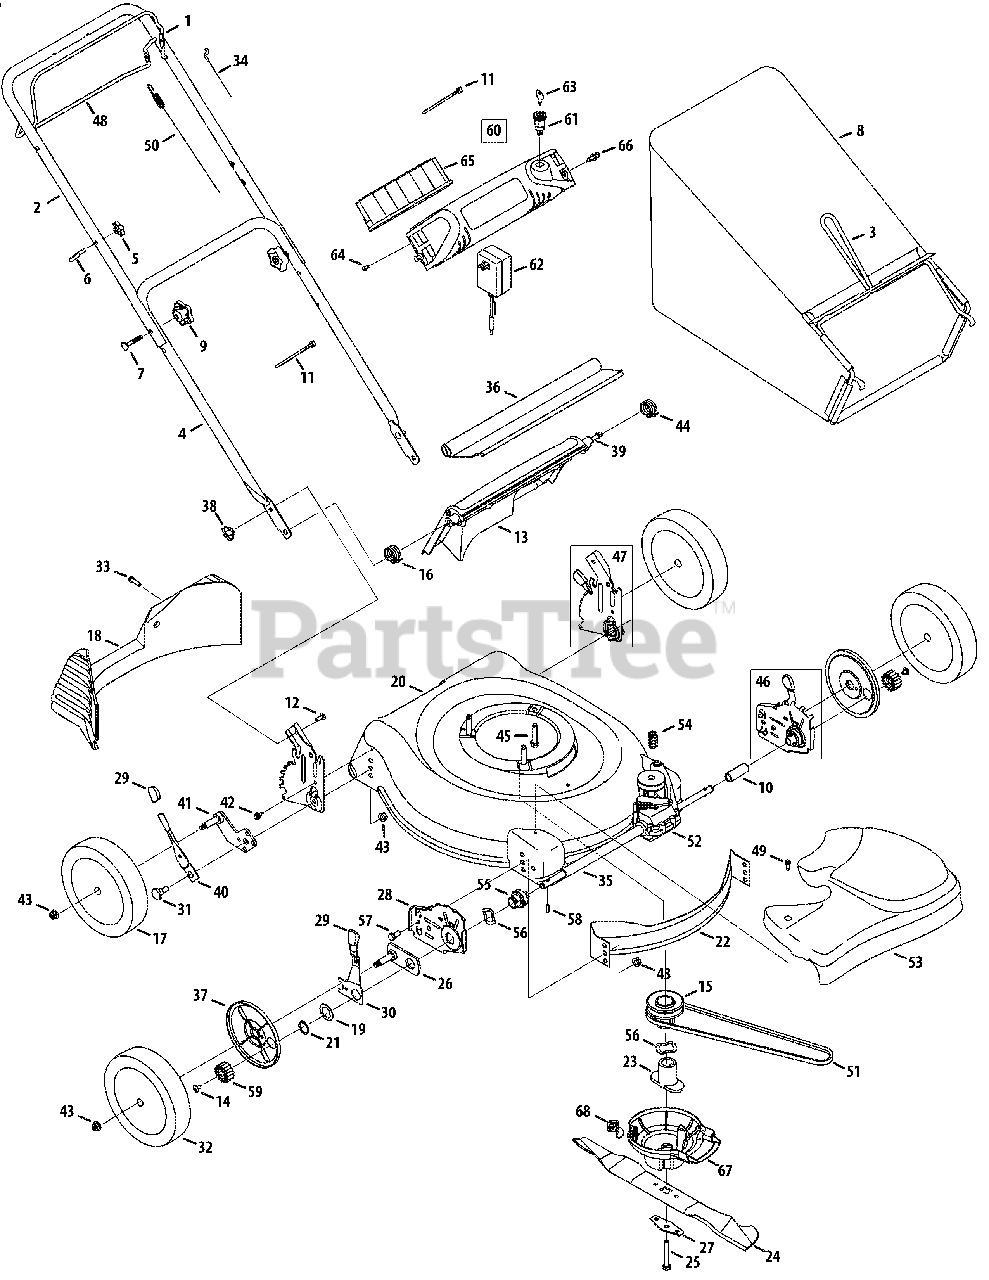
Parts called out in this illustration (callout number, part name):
5	Wing Nut
6	Rope Guide
7	Carriage Bolt,5/16-18 x 2
8	Grass Bag Assembly
9	Hand Knob
10	Sleeve Spacer - LH
11	Cable Tie
12	Carriage Bolt,1/4-20
13	Rear Discharge Door
14	Screw 1/4-20
15	Drive Pulley Assembly
16	Torsion Spring - RH
17	Rear Wheel, 8'' x 1.8''
18	Rear Baffle
19	Washer, 1.5'' OD
21	Snap Ring
22	Front Baffle
23	Blade Adapter
24	21'' Mulch Blade
25	Hex Bolt, 3/8-24 x 2.5
26	Pivot Plate Assembly
27	Blade Bell Support
28	Height Adjustment Plate - RH
28	Height Adjustment Plate - LH
29	Adjustment Lever Knob
30	Front Lever - RH
30	Front Lever - LH
31	Shoulder Screw
32	Front Wheel, 8'' x 1.8''
33	Screw, 1/4-15 x 1.000
34	Control Cable - 40.75''
35	Sleeve Spacer - RH
36	Trailshield
37	Wheel Dust Cap
38	Wing Nut, 1/4-20
39	Rear Door Pivot Rod
40	Spring Lever
41	Pivot Arm Assembly - RH
41	Pivot Arm Assembly - LH
42	AB Screw
43	Flange Lock Nut, 3/8-16
44	Torsion Spring - LH
45	TT Sems Screw, 3/8-16 x 1.00
46	Height Adjustment Assembly Front - LH
46	Height Adjustment Assembly Front - RH
47	Rear Handle Bracket Assembly - LH
47	Rear Handle Bracket Assembly - RH
48	Drive Control
49	Shoulder Screw
50	Drive Cable
51	V-Belt
52	Transmission Assembly
53	Front Driver Cover
54	Belt Tension Spring
55	Bearing Assembly
56	Wave Washer
57	Hex Screw
58	Dowel Pin
59	Gear, 14T - RH
59	Gear, 14T - LH
60	Electric Start Harness Assembly
61	Key Switch
62	Battery Charger 12V
63	Key
64	Screw, #1016 x .75
65	12 Volt Battery
66	Plastic Rivet
67	Engine Baffle
68	Engine Baffle Bracket
